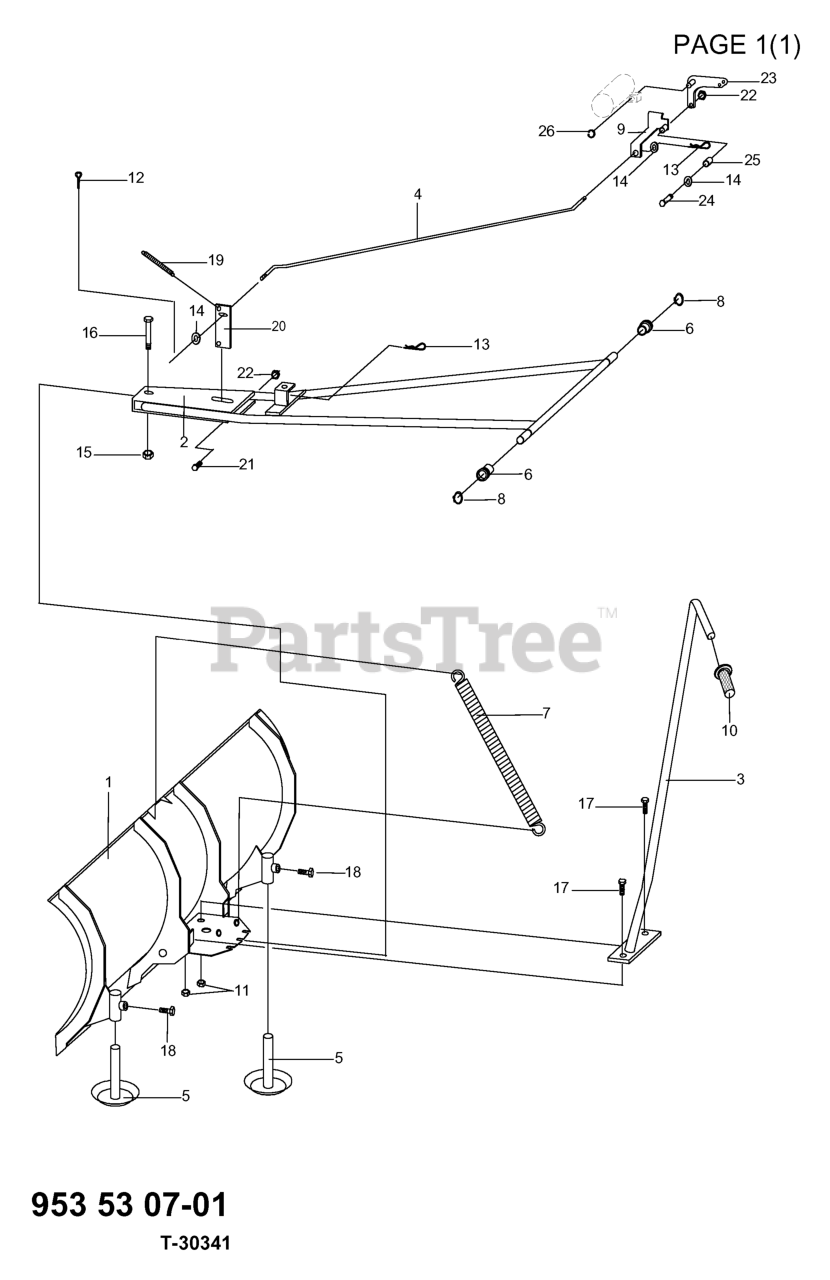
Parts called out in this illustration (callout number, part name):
5	SLIDING SHOE
12	PIN RETAINING SCREW
20	Plate, Lock
